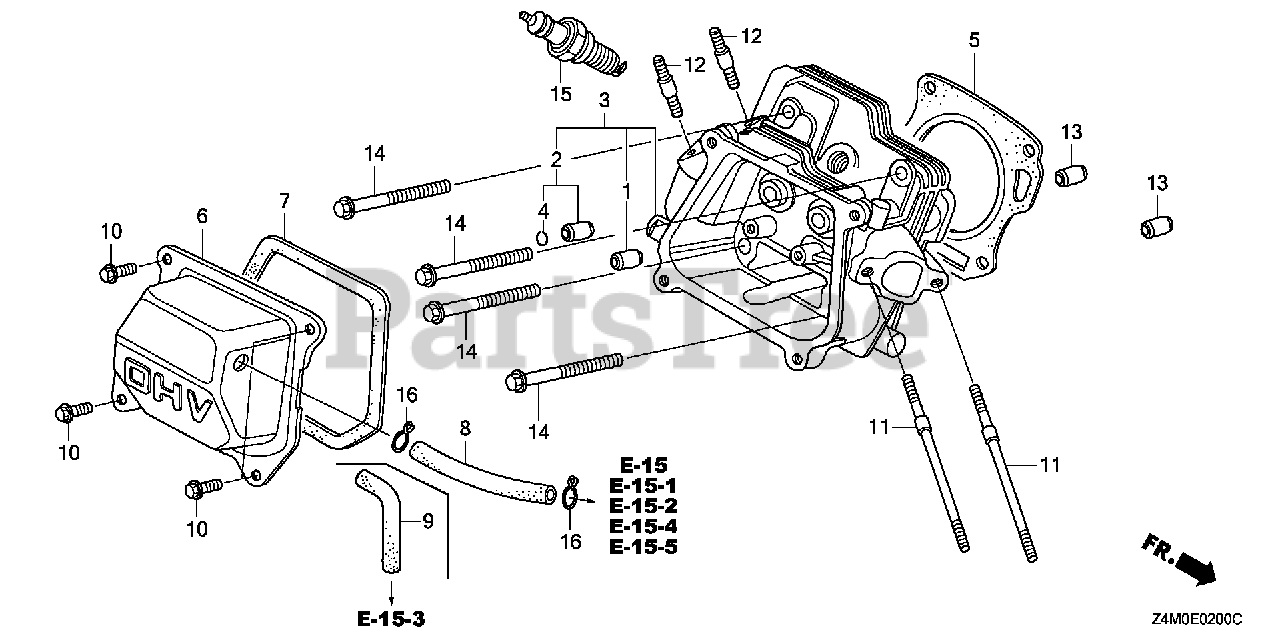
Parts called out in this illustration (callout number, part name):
1	GUIDE, VALVE (OVER SIZE) Use from Engine SN 6324986.
2	GUIDE, EX. VALVE (OS)
3	CYLINDER HEAD
4	CLIP, VALVE GUIDE Use from Engine SN 1231803.
5	GASKET, CYLINDER HEAD (NIPPON LEAKLESS)
6	COVER, HEAD
7	GASKET, CYLINDER HEAD COVER
9	TUBE, BREATHER Use from Engine SN 1556858.
10	BOLT, FLANGE (6X12) (CT200)
11	BOLT, STUD (6X94)
12	BOLT, STUD (8X32)
13	PIN A, DOWEL (10X16)
14	BOLT, FLANGE (8X60)
15	SPARK PLUG (BPR6ES) (NGK)
15	SPARK PLUG (W20EPR-U) (DENSO)
